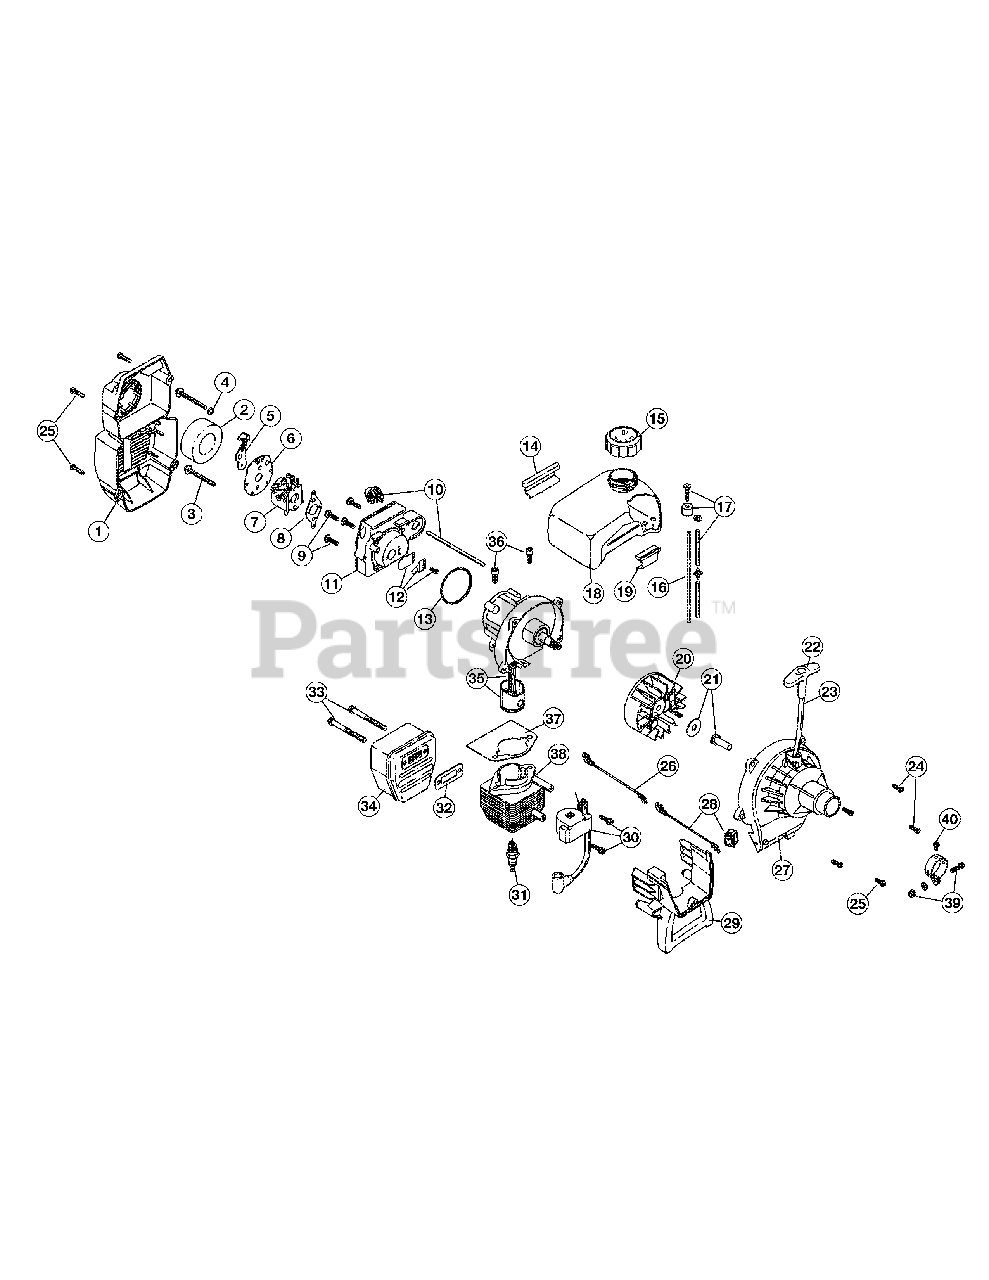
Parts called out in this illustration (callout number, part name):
1	Air Cleaner Cover Assembly
2	Air Cleaner Filter
3	Carburetor Mounting Screws
4	Wavey Washer
5	Choke Lever Assembly
6	Choke Lever & Plate
7	Carburetor Assembly
8	Carburetor Gasket
9	Carb Mount Screw
10	Primer and Hose Assembly
11	Carburetor Mount Assembly
12	Reed Assembly
13	O-Ring
14	Rear Mounting Pad
15	Fuel Cap Assembly
16	Fuel Return Line
17	Fuel Line Assembly
18	Fuel Tank Assembly
19	Front Mounting Pad
20	Flywheel Assembly
21	Square Nut Drive
22	Pull Handle
24	Housing Screw
25	Cover Screw
26	Wire Lead
27	Starter Housing Assembly
29	Shroud Extension and Stand
30	Module Assembly
31	Spark Plug
32	Exhaust Gasket
33	Muffler Mounting Bolt
34	Muffler Assembly
35	Piston & Rod Assembly
36	Cylinder Bolt
37	Cylinder Gasket
38	Cylinder Assembly
39	Clamp Assembly
